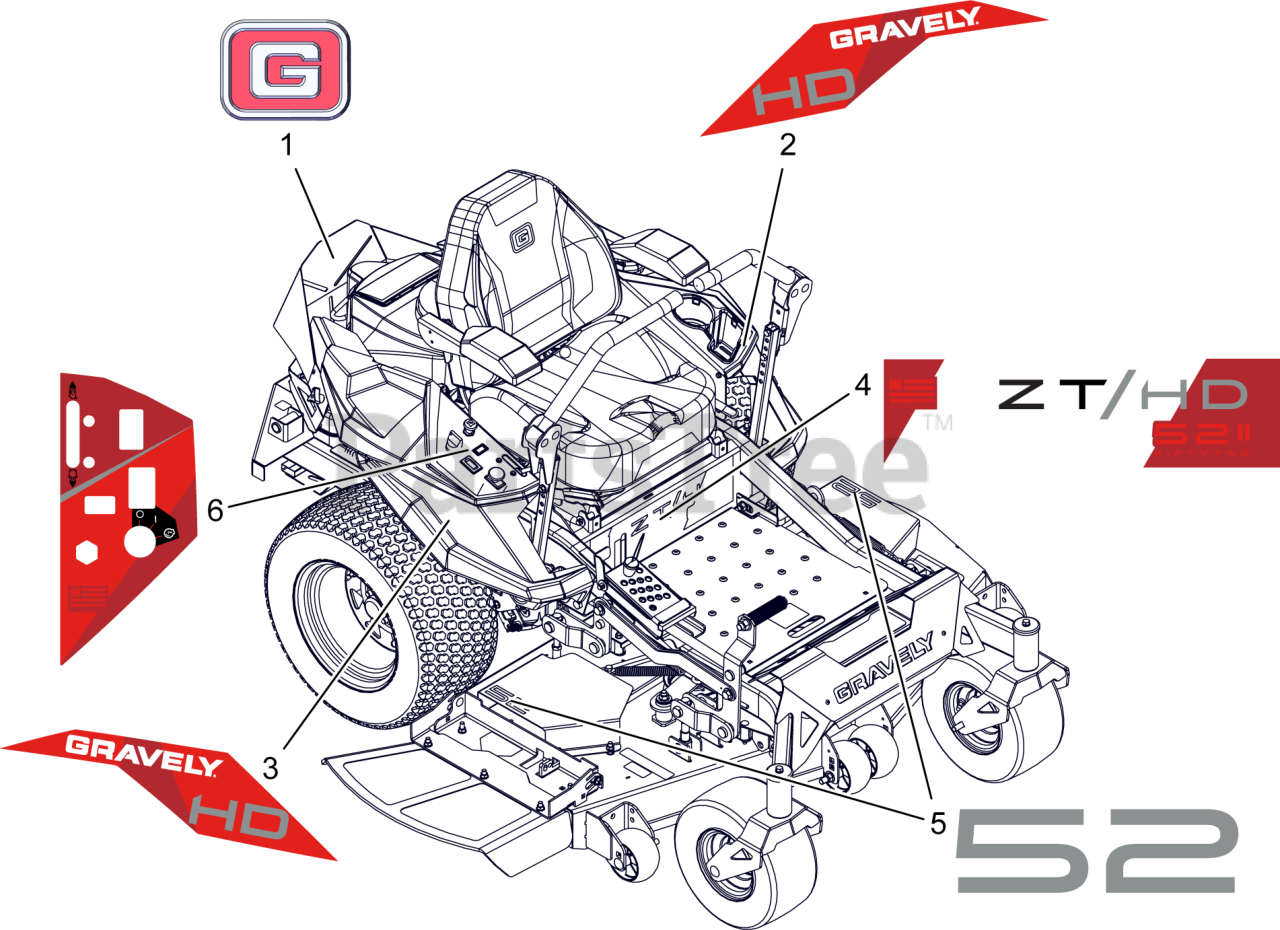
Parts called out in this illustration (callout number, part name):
1	DECAL, GRAVELY BRAND
2	DECAL, FENDER LH - HD
3	DECAL, FENDER RH - HD
4	DECAL, ZT/HD - 52
5	DECAL, DECK - 52
6	DECAL, CONTROL PANEL
